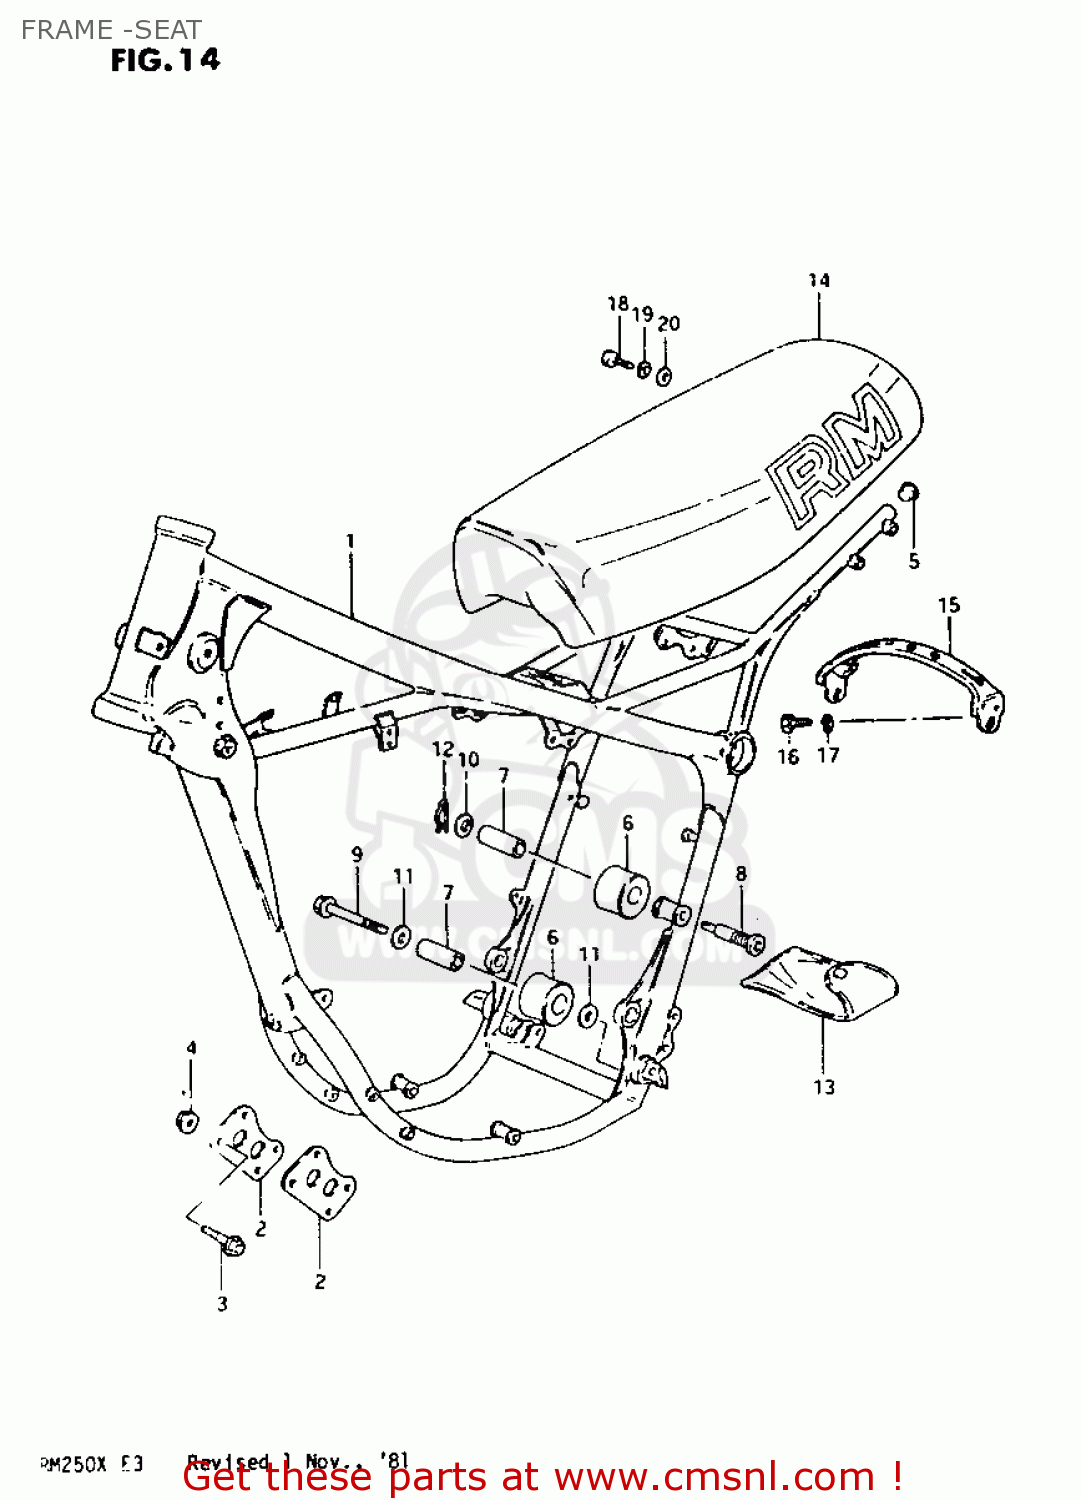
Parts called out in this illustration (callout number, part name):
1	FRAME
2	PLATE,ENGINE MOUNTING
3	BOLT(8X75)
4	NUT
5	PLUG(OD:17)
6	ROLLER,CHAIN LENGTH CONTROL
7	SPACER,CHAIN LENGTH ROLLER
8	BOLT,CHAIN LENGTH ROLLER
9	BOLT(8X45)
10	WASHER
11	WASHER
12	CLIP
13	TOOL SET
14	SEAT ASSEMBLY
15	PLATE SEAT REAR STAY
16	BOLT
17	WASHER,LOCK
18	BOLT
19	LOCK WASHER
20	WASHER (8.2X20X1.6)
